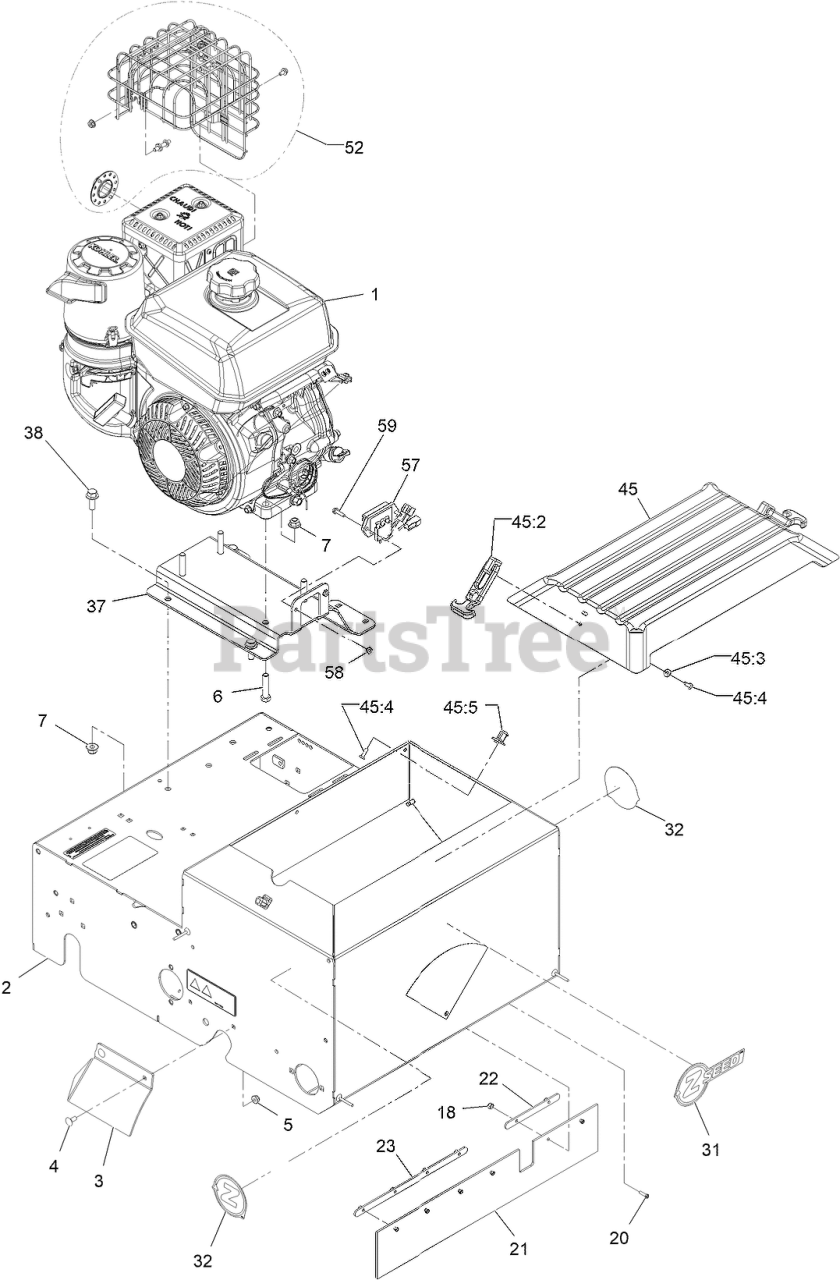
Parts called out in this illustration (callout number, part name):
1	Frame-Service ASM
3	SCREW-CARR
5	SCREW-HH
6	NUT-HF, NI
7	NUT-LOCK
18	SCREW-SHH
20	GUARD-DUST
21	PLATE-RETAINER
22	PLATE-RETAINER
23	DECAL-Z-SEED LOGO
31	Decal-Z-Logo
32	Plate-Engine
37	SCREW-HHF 3/8-16 X 1
38	SEEDER COVER KIT
45	LATCH-RUBBER
45:2	WASHER-FLAT
45:3	SCREW-PPH
45:4	LATCH-KEEPER
45:5	KIT-CH395 MUFFLER GUARD
52	Regulator
57	KEPS Nut
58	SCREW-HWH
59	SCREW-HWH
